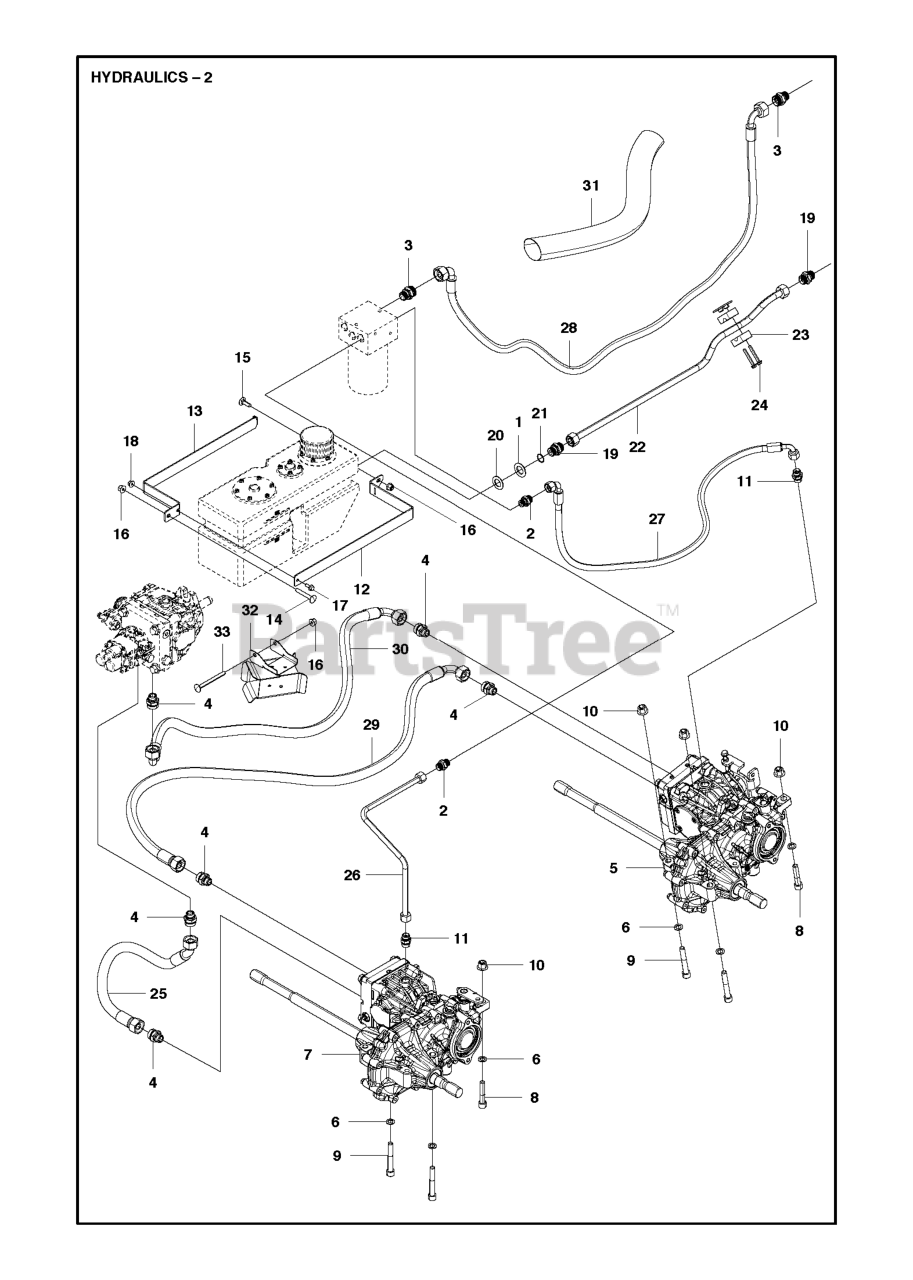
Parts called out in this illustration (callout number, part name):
16	NUT FLANGE
17	BOLT FLANGE - M6X20
18	NUT FLANGE
